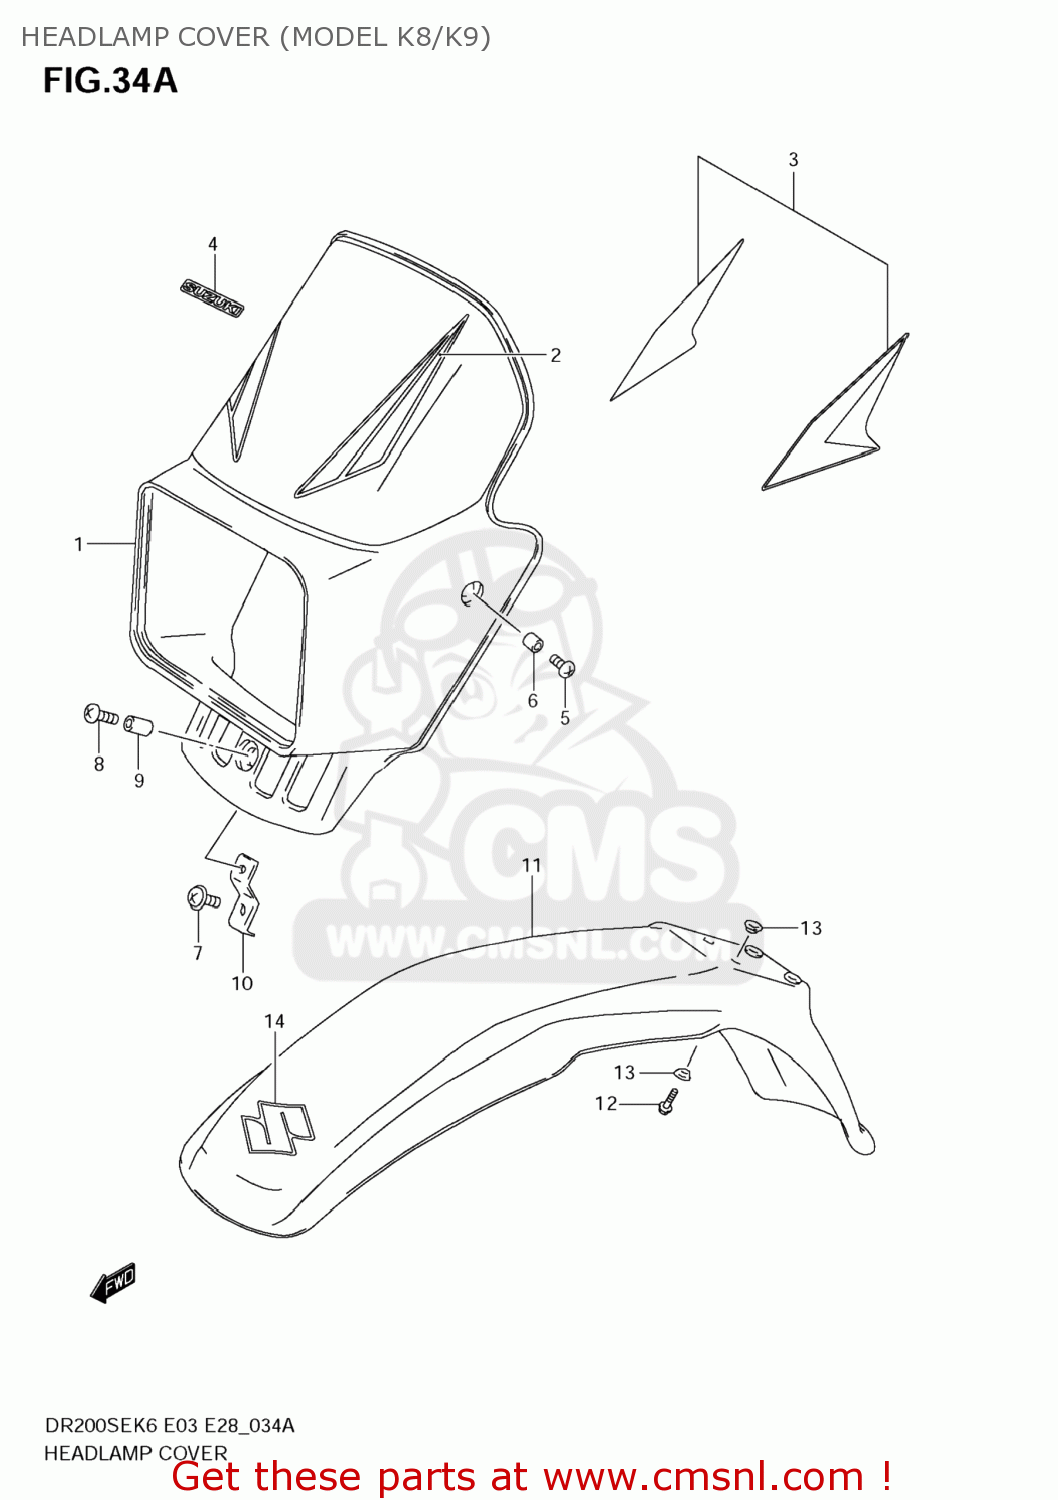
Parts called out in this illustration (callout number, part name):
1	COVER,HEADLAMP
2	TAPE SET,HEADLAMP COVER
3	TAPE SET,HEADLAMP COVER
4	EMBLEM,SUZUKI
5	SCREW
6	SPACER(6.1X8X3.5)
7	SCREW
8	SCREW
9	SPACER(6.1X8X12)
10	BRACE,HEADLAMP HOUSING LWR
11	FENDER,FR
12	BOLT
13	WASHER
14	EMBLEM,S
